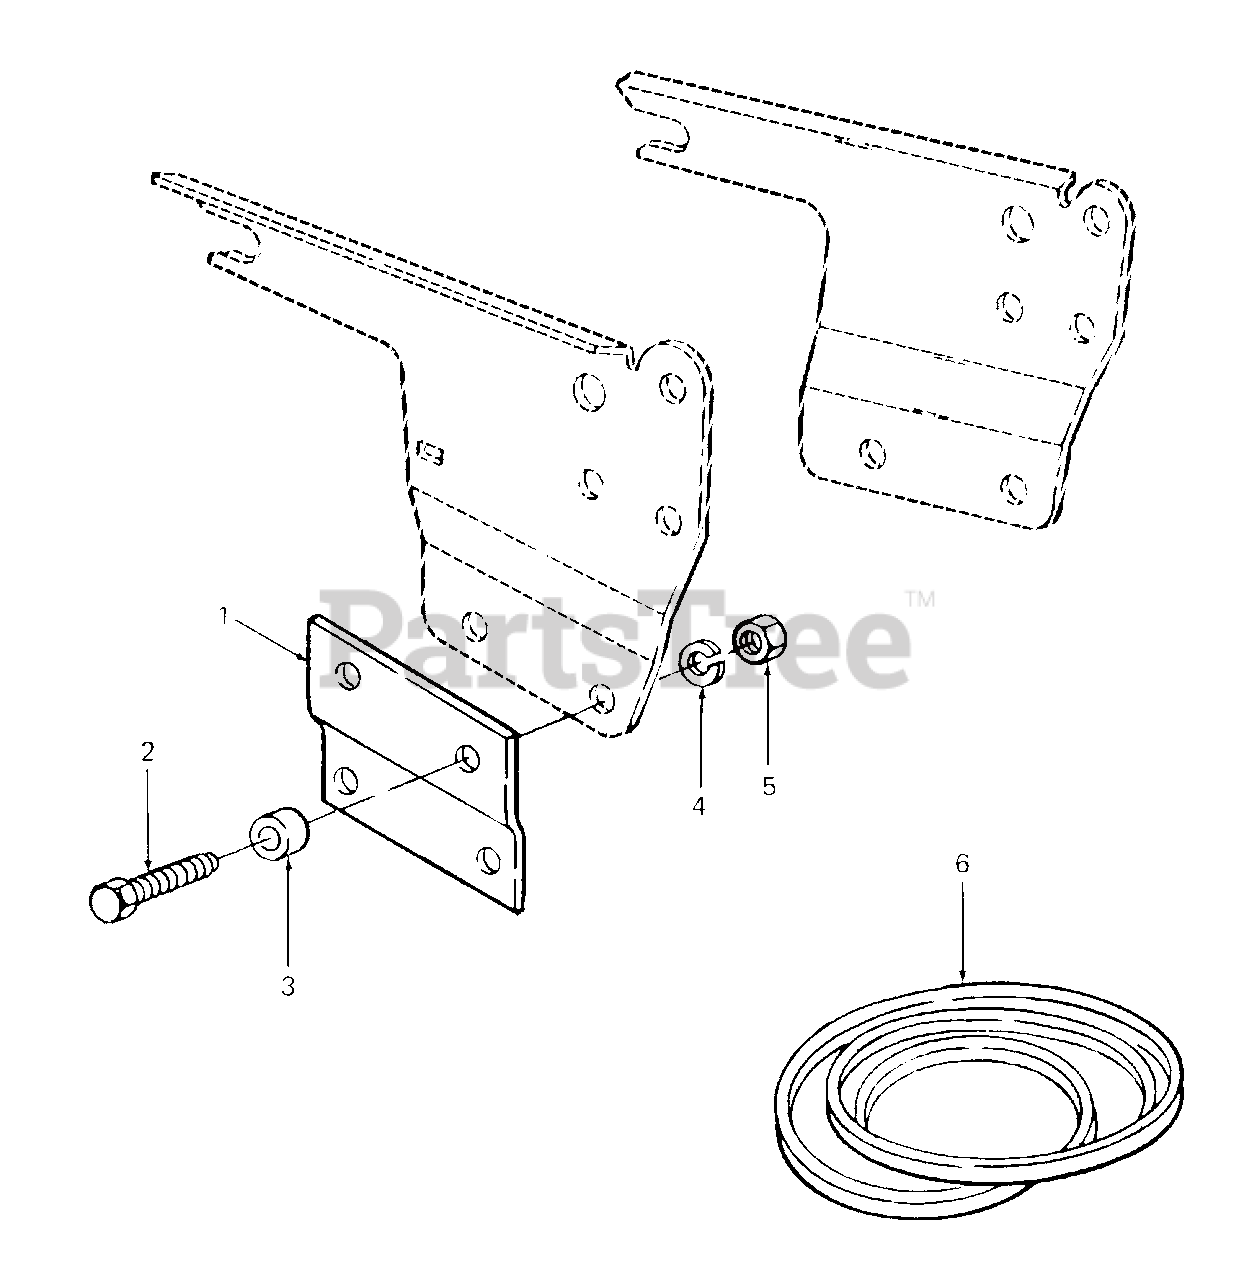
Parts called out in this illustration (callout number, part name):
3	Spacer, .635 X .88 X .25 Lg
4	Washer, Lock, 5/8
5	Nut, Hex Jam, 5/8-18
6	V-Belt, B-Section X 91.5 Lg
